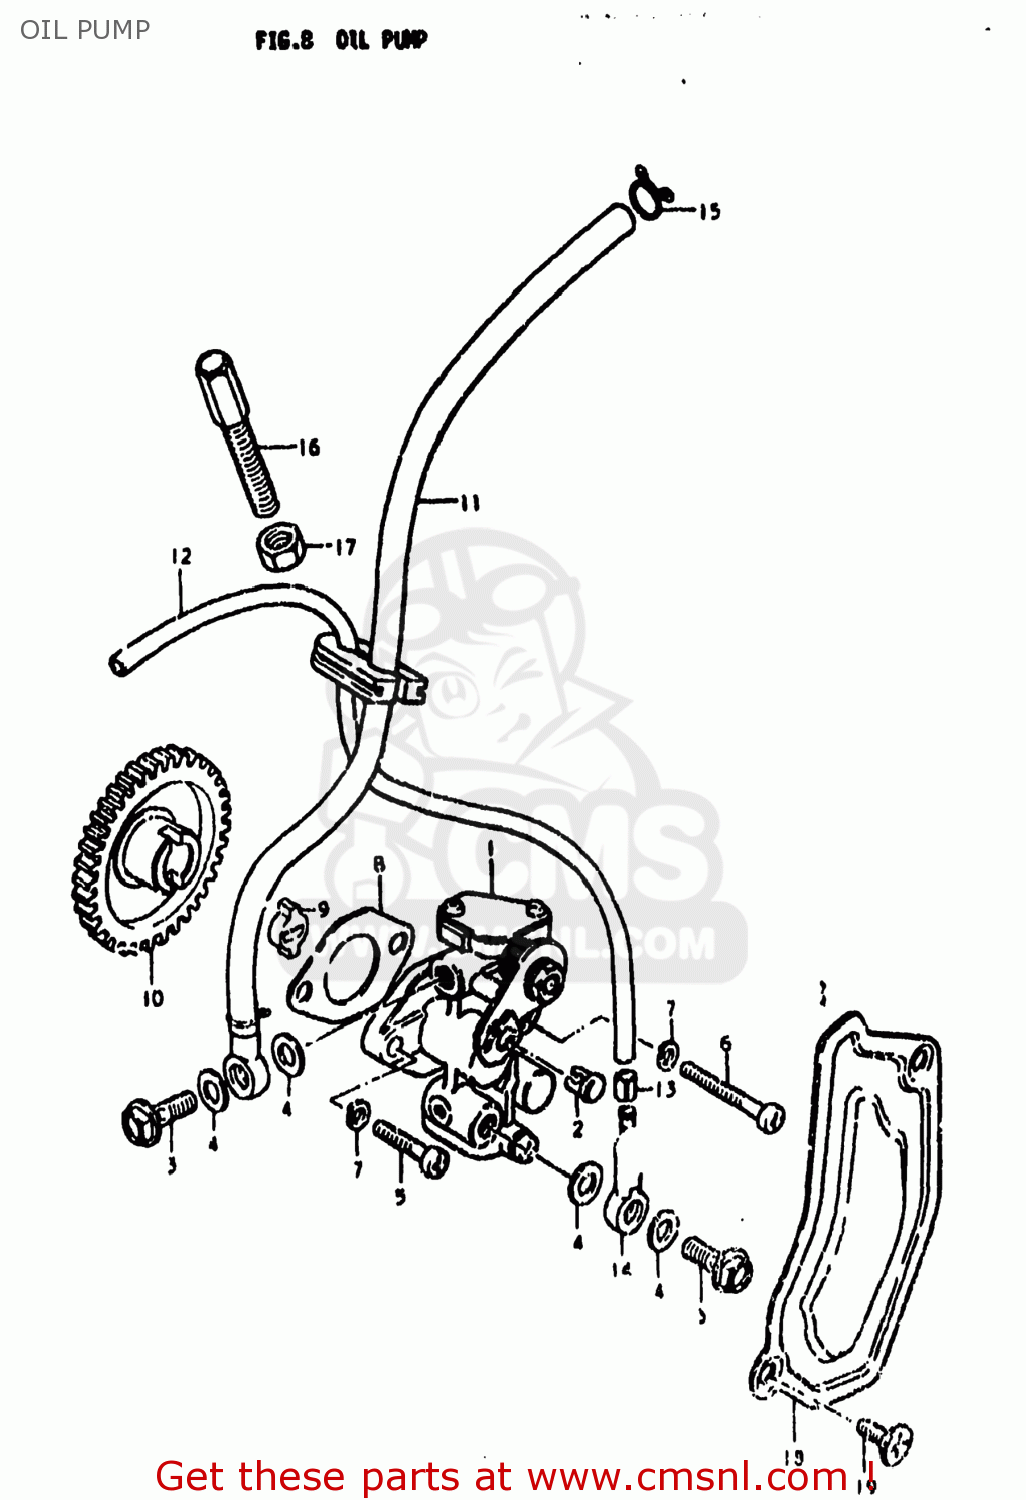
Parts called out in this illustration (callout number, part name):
1	PUMP ASSEMBLY,OIL
2	TERMINAL,CABLE
3	UNION BOLT
4	GASKET(6.2X11X1).2 (NAS)
5	SCREW
6	SCREW
7	LOCK WASHER
8	GASKET,OIL PUMP (MCA)
9	PIECE,OIL PUMP DRIVE
10	GEAR,OIL PUMP DRIVE
11	HOSE,OIL NO.1
12	HOSE,OIL
13	CLIP
14	VALVE,CHECK
15	CLIP
16	BOLT
17	NUT
18	CAP,OIL PUMP INSPECTION
19	SCREW
